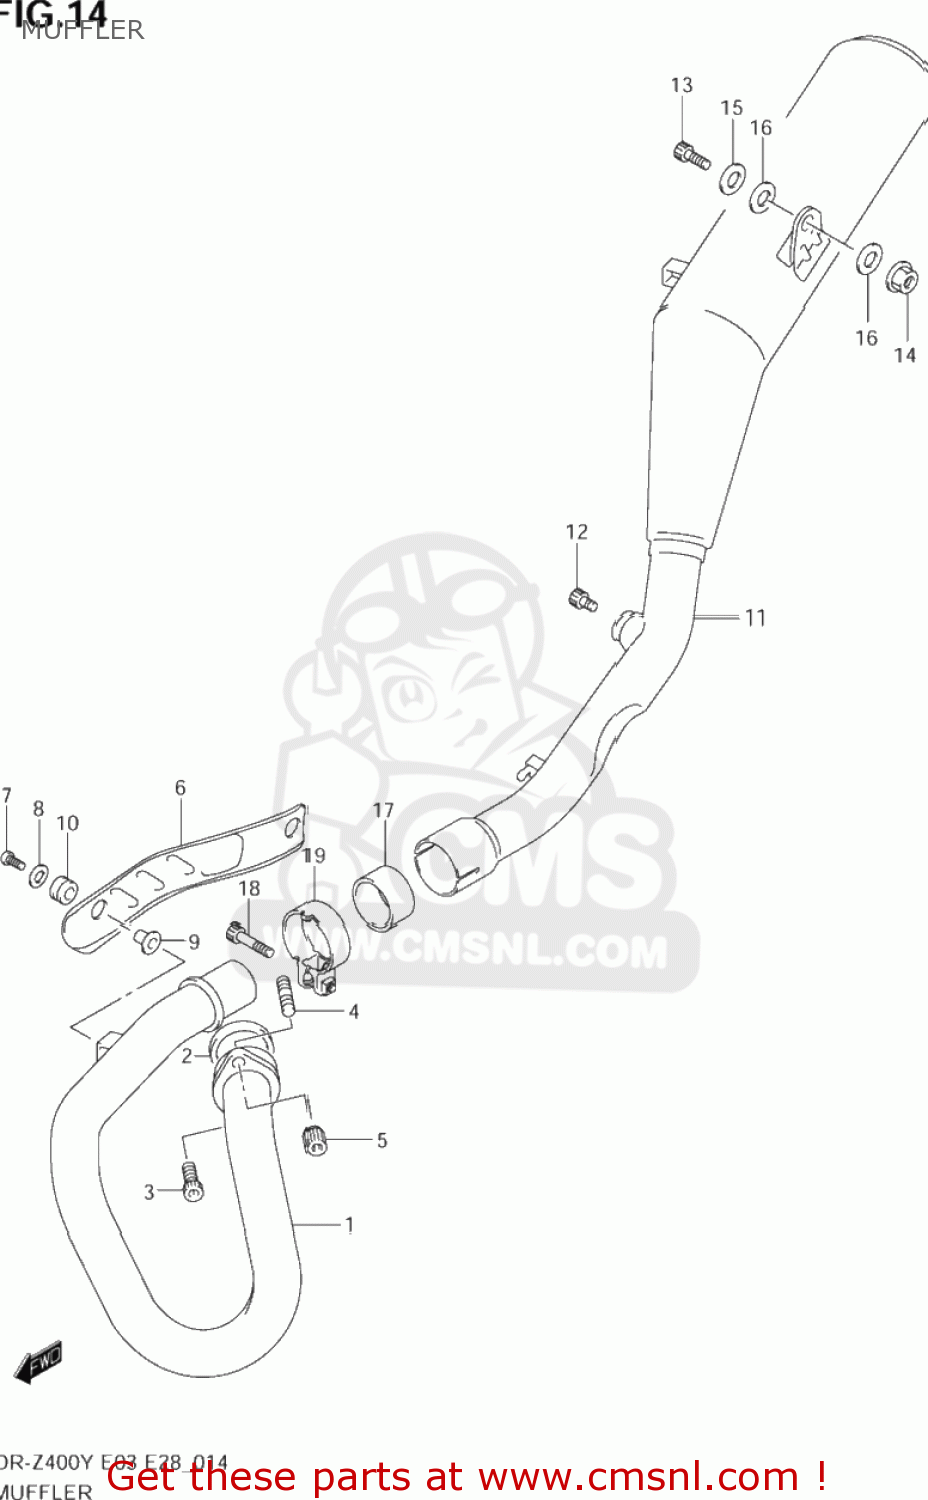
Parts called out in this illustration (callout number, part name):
1	PIPE,EXHAUST
2	GASKET,EXHAUST PIPE
3	BOLT
4	BOLT
5	NUT
6	COVER,EXHAUST PIPE
7	SCREW(6X16)
8	WASHER(6.5X18X1)
9	SPACER(6.2X8.4X6.9)
10	CUSHION
11	BODY,MUFFLER
12	BOLT
13	BOLT
14	NUT
15	WASHER(8.5X24X2.3)
16	WASHER
17	CONNECTOR,MUFFLER JOINT
18	BOLT
19	CLAMP,MUFFLER CONNECTOR
